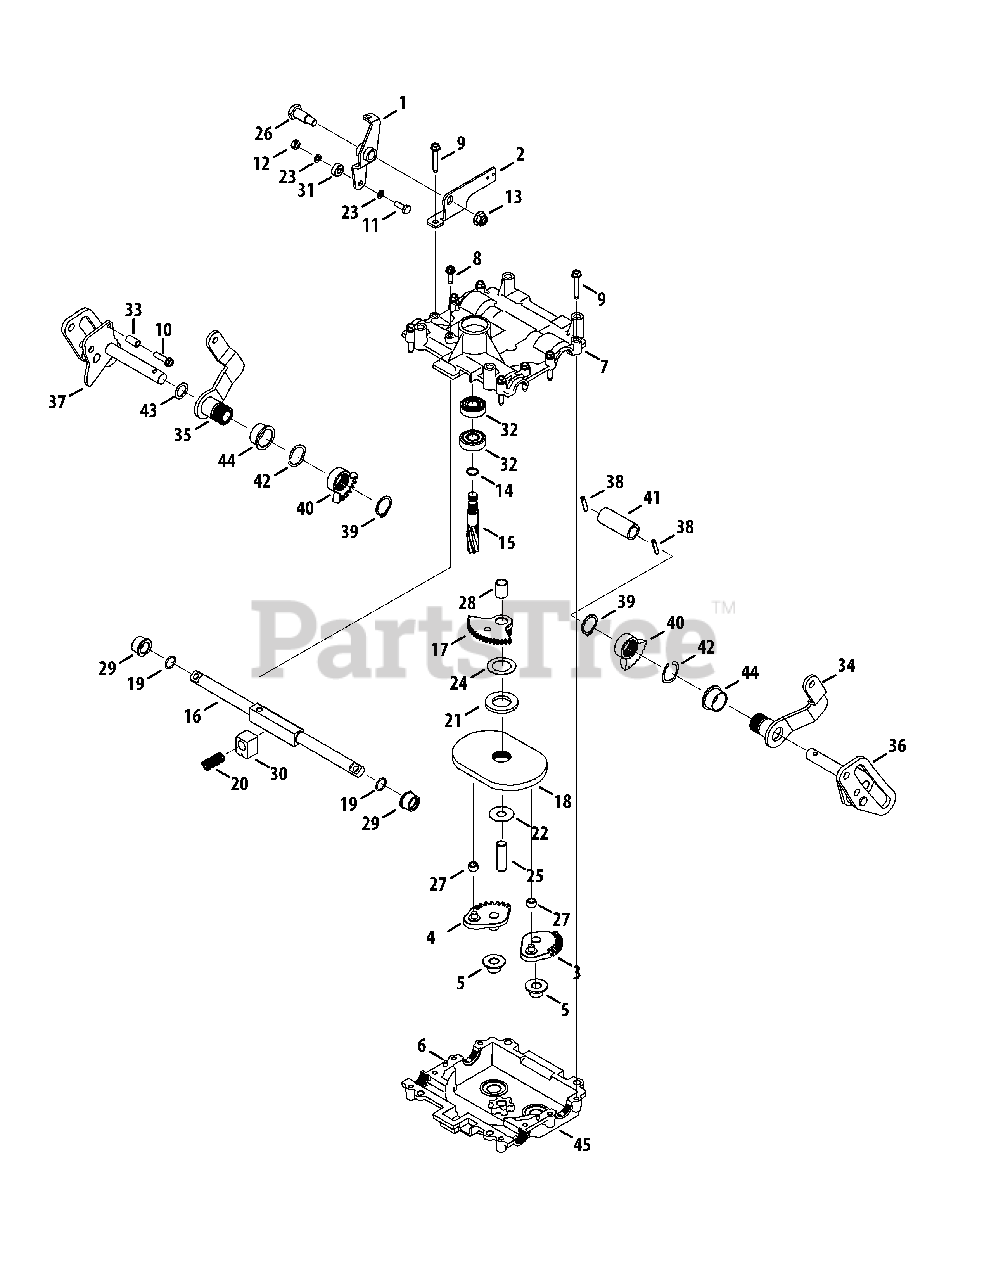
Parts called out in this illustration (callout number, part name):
1	Cam Plate Assembly
2	Neutral Bracket
3	LH Steering Gear Assembly
4	RH Steering Gear Assembly
5	Flange Bearing, .5 x .700
6	Dowel Pin, 3/16 x 1/2
7	Upper Steering Housing
8	Hex Washer Screw, 1/4-20 x 0.750
9	Hex Washer Screw, 1/4-20 x 1.500
10	Hex Washer Screw. 1/4-20 x 1.000
11	Hex Screw, 1/4-20 x .75
12	Flange Lock Nut, 1/4-20
13	Flange Lock Nut, 3/8-16
14	Retaining Ring, .56
15	Pinion Gear, 7-Tooth
16	Synchro Rack Gear
17	Steering Gear, 53-Tooth
18	Hydro Steering Cam
19	O-Ring, .625 x .07
20	Compression Spring, .531 x 1.25
21	Flat Washer, 1.01 x 1.75 x .172
22	Flat Washer, .508 x 1.325 x .040
23	Flat Washer, .260 x .455 x .048
24	Thrust Washer, 1.007 x 1.542 x .03
25	Steering Shaft
26	Shoulder Screw, 3/8-16 x .500 x .835
27	Sleeve Bearing, .437 x .3425
28	Sleeve Bearing, .623 x .5025 x .800
29	Flange Bearing, .625 x .875
30	Rack Caster Bearing
31	Ball Bearing, .25 x .6875 x .25
32	Ball Bearing, .5625 x 1.375 x .4375
33	Spacer, .260 x .375 x .75
34	Arm Asm, Lh, Hydro, Vert
35	Arm Asm, Rh, Hydro, Vert
36	Cam Asm, Lh, Painted
37	Cam Asm, Rh, Painted
38	Pin, Spirol, 3/16 X 1.00, Hd
39	Ring, Snap, 1.0 Dia Shaft
40	Gear, Steering, 26t
41	Tube, Cam, Speed
42	Spring, Wave, M, 24.22x32x1.98, Gap
43	Wash, Flat, .635x.930x.033, Ht
44	Brg, Sleeve, 1.2 Od X 1.00 Id
45	Lower Steering Housing
